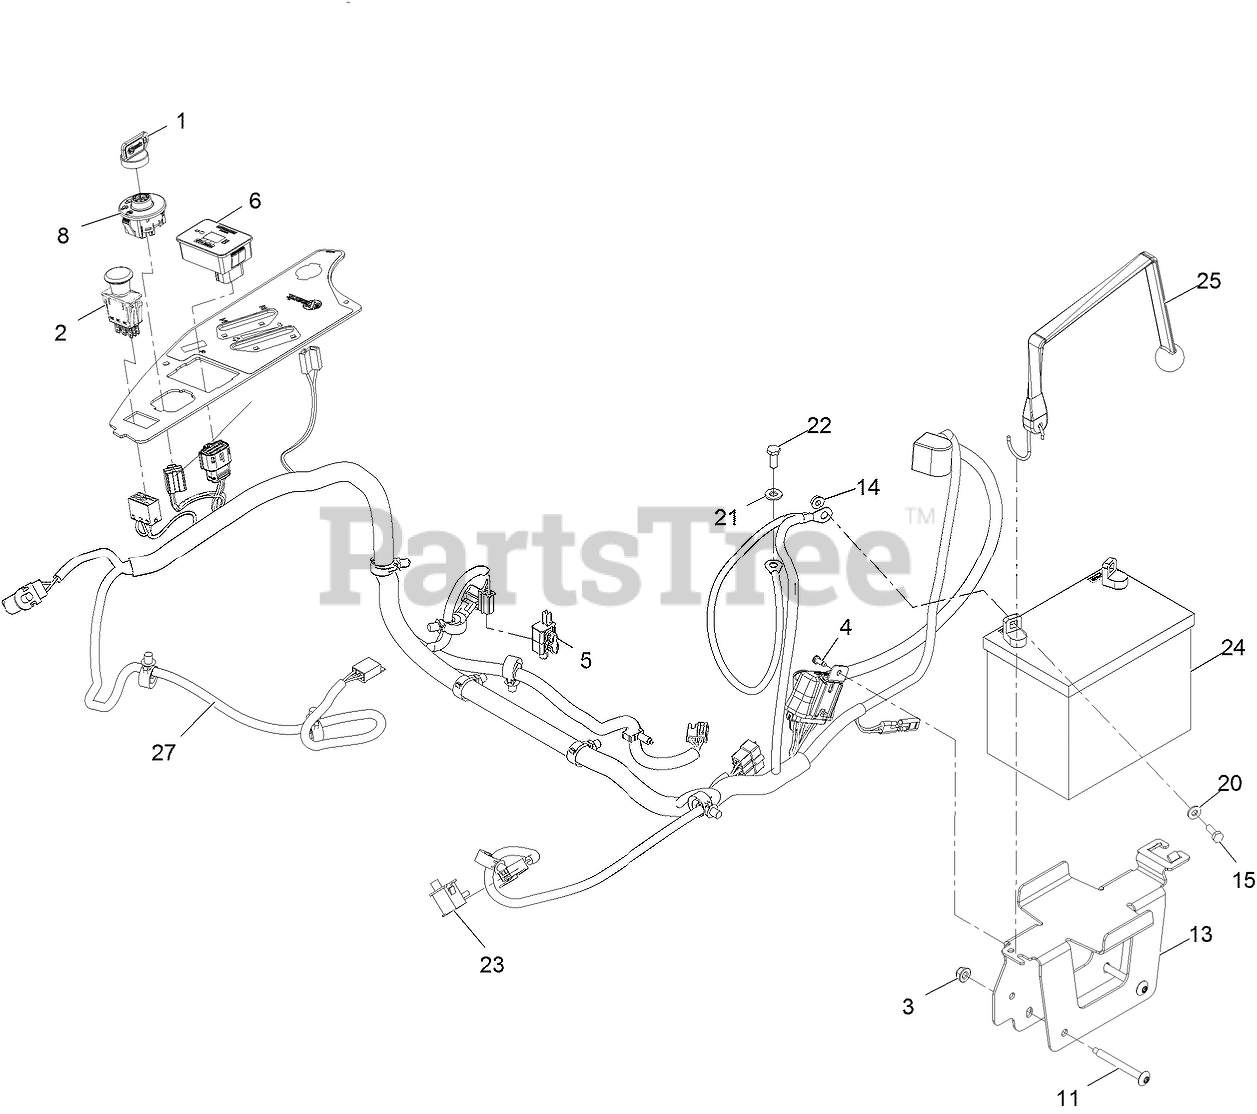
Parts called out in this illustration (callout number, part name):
1	KEYS-IGNITION (SPARE PAIR
1	KEY-IGNITION
2	SWITCH-PTO
3	NUT-HF, NI
4	SCREW-FORMING, THREAD
6	MODULE ASM
8	SWITCH-IGNITION
11	SCREW-TORX
13	TRAY-BATTERY
15	SCREW-HH
20	WASHER-FLAT
21	WASHER-PLAIN
22	SCREW-HH
23	SWITCH-BAIL
24	Battery
25	STRAP-BUNGEE
27	HARNESS - WIRING
